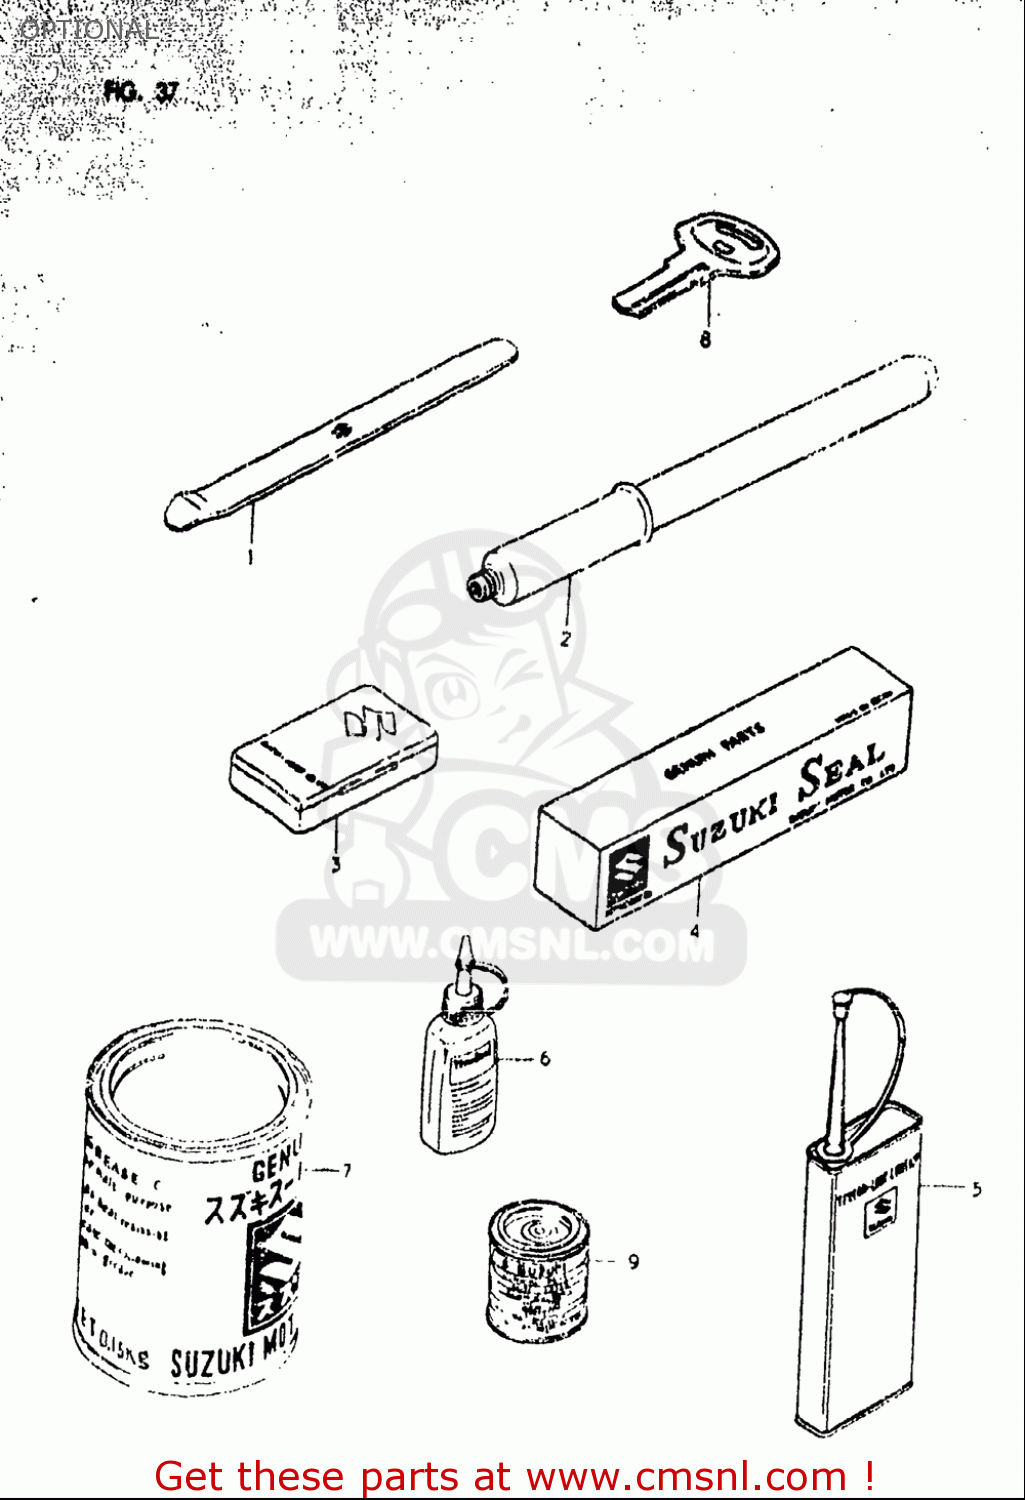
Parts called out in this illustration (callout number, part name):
1	LEVER,TIRE
5	THREAD LOCK NO.1303B PURPL 50G
6	THREAD LOCK NO.1401 CLEAR 200G
7	GREASE(C)EP2 LITHIUM 150G
8	KEY,BLANK
